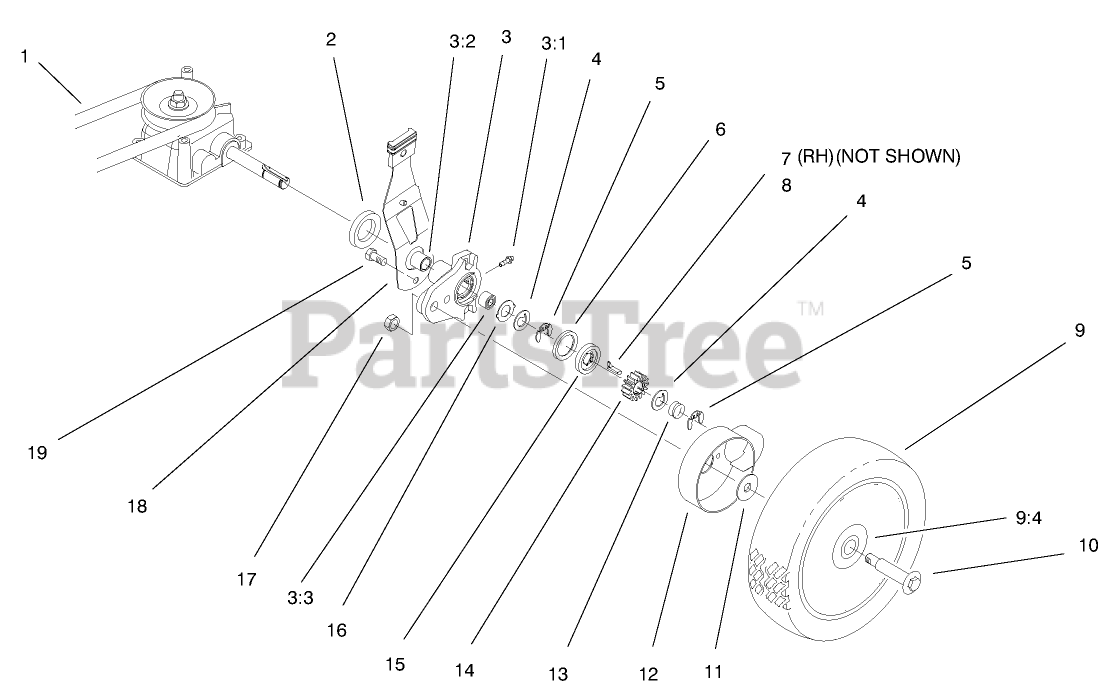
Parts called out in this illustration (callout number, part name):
1	V-BELT
2	SPACER-SHAFT, AXLE
3	REAR HEIGHT ADJUSTMENT ARM ASM
3:1	FITTING-GREASE
3:2	BUSHING
3:3	BUSHING
4	WASHER-THRUST, KEYED
5	RING-RETAINING,CLIP
6	RING-FRICTION
7	KEY-ROCKING, RH
8	KEY-ROCKING, LH
9	WHEEL ASM
9:4	BUSHING
10	BOLT-SHOULDER
11	WASHER-STEPPED
12	COVER-WHEEL
13	SPRING-COMPRESSION
14	GEAR-PINION
15	WASHER-CLUTCH
16	WASHER-ARM, PIVOT
17	NUT-JAM, LOCKING
18	REAR SPRING ARM ASM
19	SCREW-HWH
